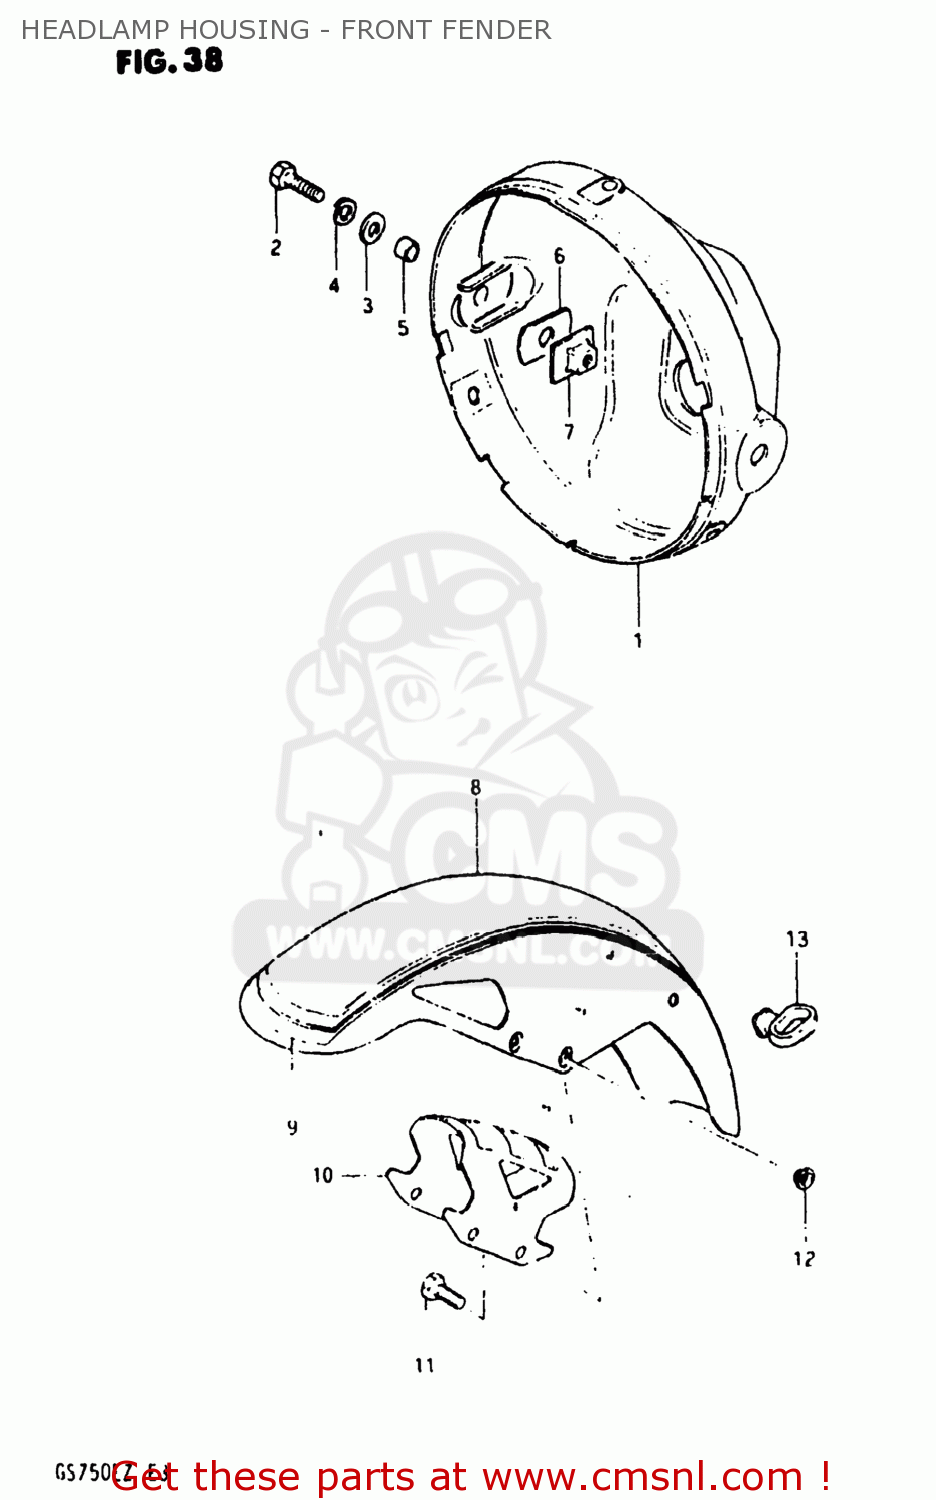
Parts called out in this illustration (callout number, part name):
1	HOUSING,HEADLAMP
2	BOLT
3	WASHER
4	LOCK WASHER
5	SPACER (8.8X12X7)
6	CUSHION
7	PLATE,HEADLAMP HOUSING
8	FENDER,FRONT
9	TAPE SET,REAR FENDER
10	BRACE,FRONT FENDER
11	BOLT 8X16
12	WASHER
13	GUIDE,CABLE
